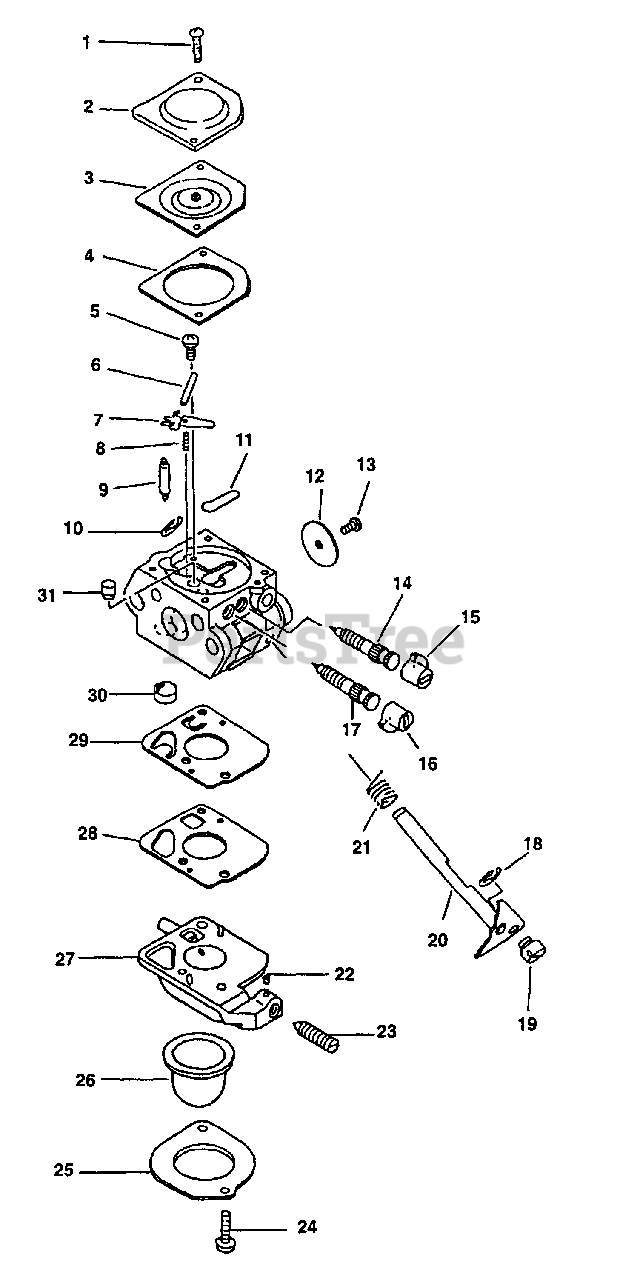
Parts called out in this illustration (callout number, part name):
2	COVER, METERING DIAPHRAGM
3	DIAPHRAGM, METERING
4	GASKET, METERING
6	PIN, METERING LEVER
7	LEVER, METERING
8	SPRING, METERING LEVER
9	VALVE, INLET NEEDLE
11	PLUG, WELCH
12	VALVE, THROTTLE
14	NEEDLE, LOW SPEED
15	CAP, LIMITER - WHITE
16	CAP, LIMITER - RED
17	NEEDLE, HIGH SPEED
20	SHAFT, THROTTLE
21	SPRING, THROTTLE RETURN
22	PIECE, FRICTION
23	SCREW, IDLE ADJUST
25	RETAINER
26	BULB, PURGE
27	BODY ASSY, PURGE
28	GASKET, PUMP
29	DIAPHRAGM, PUMP
30	STRAINER
31	NOZZLE, CHECK VALVE
